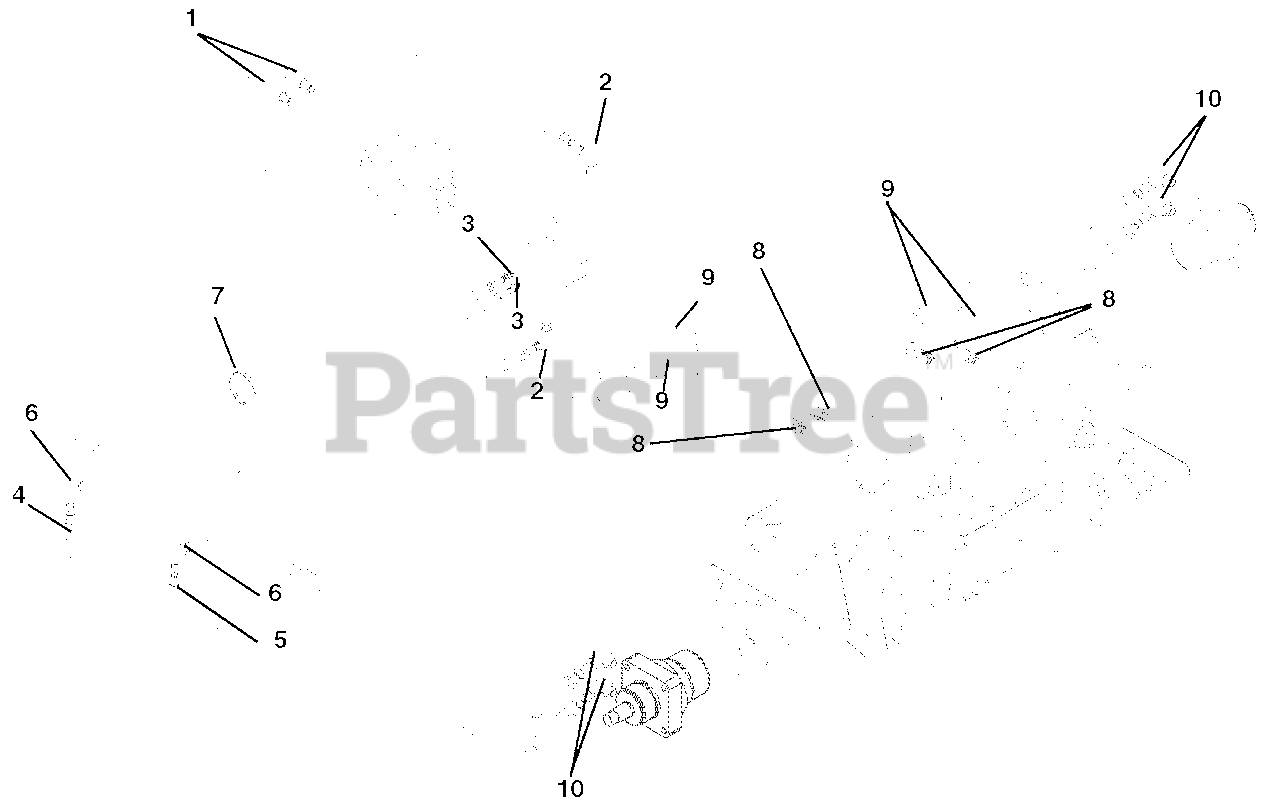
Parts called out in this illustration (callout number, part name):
1	HOSE,HYD.25-22-2K F04F9-F06FO
2	FTG, HYD ELBOW M6F-M8O
3	FITTING, HYD (4-6 F5OLO)
4	HOSE,HYD.25-42-2K F04F0-F04F4
5	HOSE,HYD .25-47-2K F04F0-F04F4
6	FITTING, HYD (4 C5OLO)
7	CABLE TIE LG 5-1/2
8	ADPTR,FACE SEAL 8X8 1/2 O-RING
9	HOSE,HYD .50-17-2K F08F0-F08F9
10	FITTING, HYD (8-10 V5OLO)
